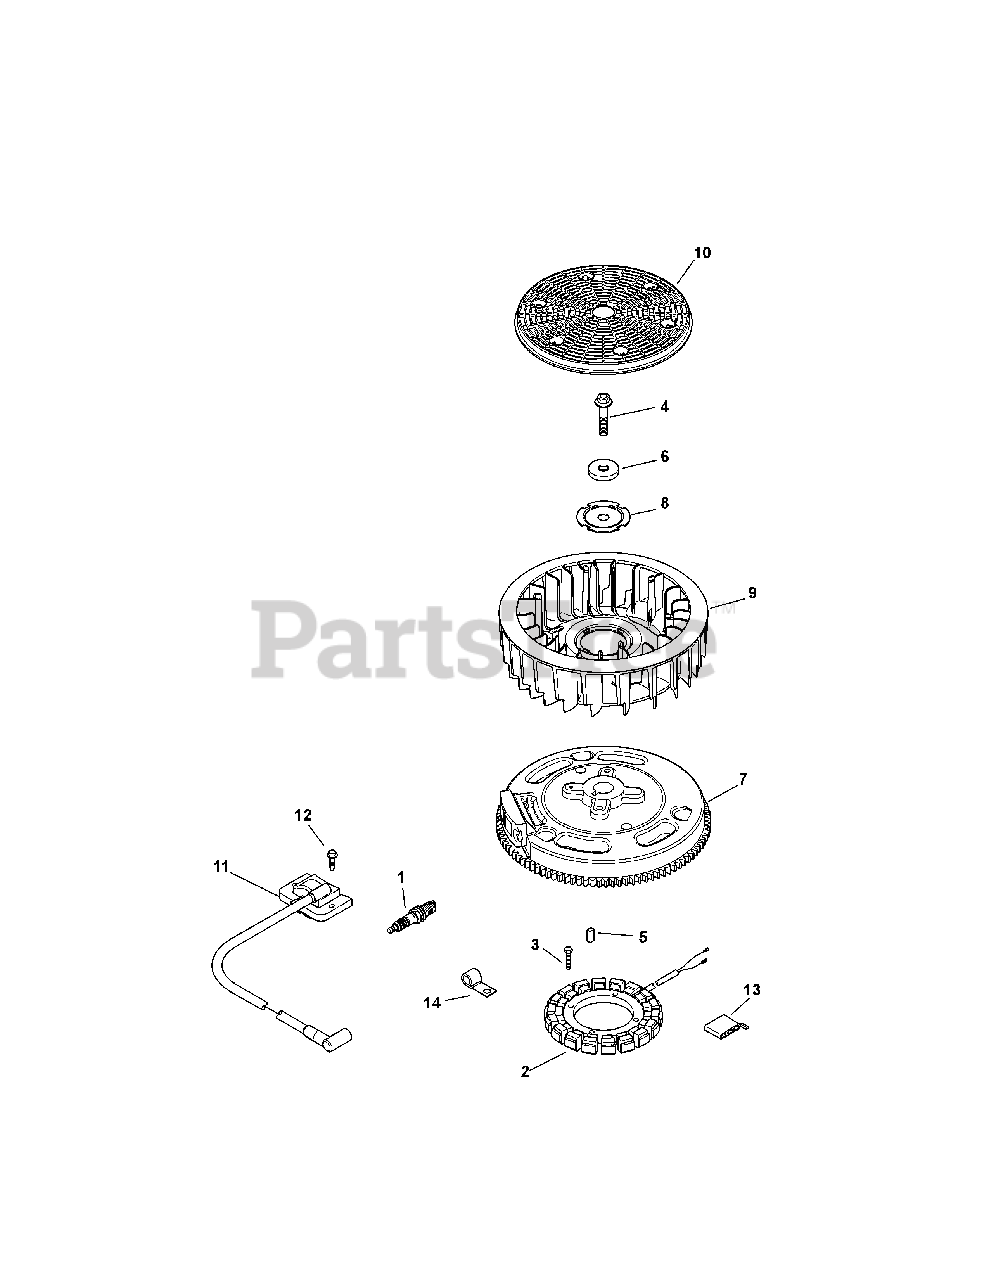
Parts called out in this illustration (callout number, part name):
1	Spark Plug
2	15 Amp Stator Kit
3	Screw, M5 x 0.8 x 25
4	Hex Flange Screw
7	Flywheel Assembly
8	Fan Mounting Plate
9	Fan
11	Module Ignition Kit
12	Screw, M5 x .8 x 20
